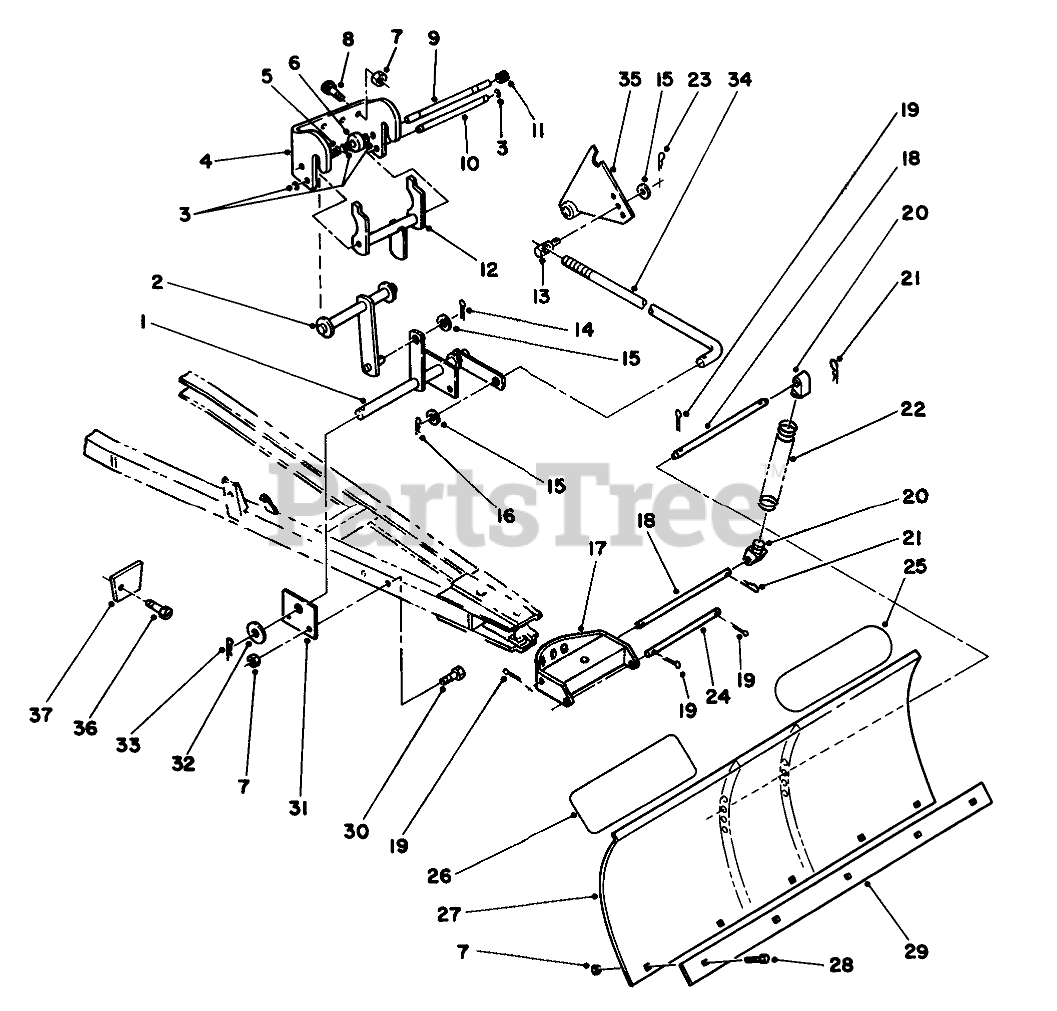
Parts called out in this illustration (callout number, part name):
1	Lift Arm
2	Arm
3	RING-RETAINING
4	Housing-Front Hitch
5	SPRING
7	NUT-LOCK, NI
8	SCREW-CARR
9	ROD-LOCK
10	ROD-LATCH PIVOT
11	CAP-ROD, PLUNGER
12	Assy-Latch
13	STUD-TRUNION
14	PIN-COTTER
15	WASHER-FLAT
16	Hairpin
17	Decal
18	ROD-PIVOT, BLADE
19	PIN-COTTER
20	Lug
21	Hairpin
22	Spring
23	Hairpin
24	ROD-LOWER
25	Decal
26	DECAL-DANGER
27	Blade
28	SCREW-CARR
29	Blade Edge Plate
30	SCREW-HH
31	Plate
32	WASHER-FLAT
33	PIN-COTTER
35	Plate
36	Screw
37	Stop-Steering Spindle
